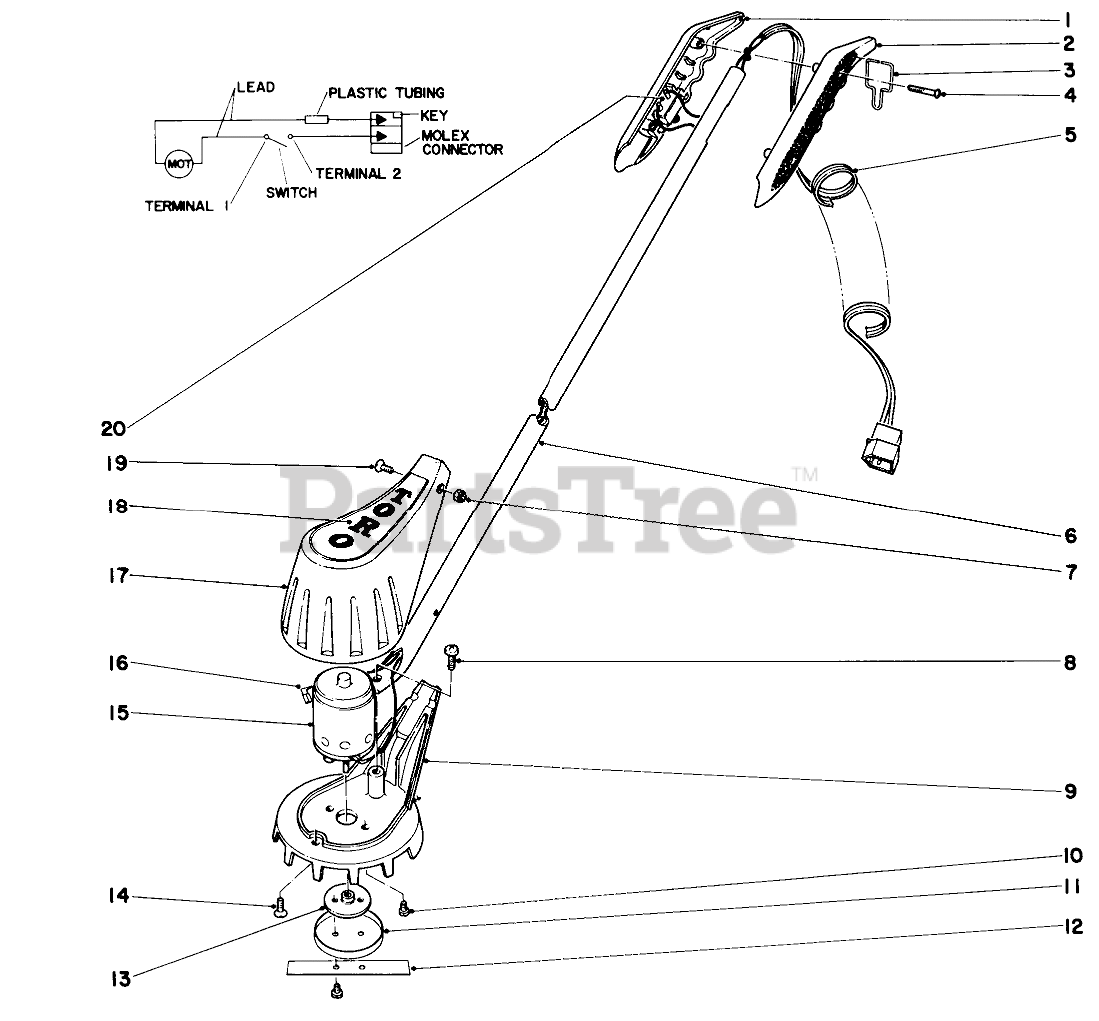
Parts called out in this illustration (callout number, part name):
1	Handle Trimmer Right Hand
2	Handle Trimmer Left Hand
3	Ring Hanger
5	Cord Assembly
6	Tube Handle
7	NUT-HEX
9	Trimmer Lower Housing
11	Grass Cup
12	Blade
13	Blade Retainer
15	Motor Trimmer
16	Lead Wire
17	Trimmer Upper Housing
18	Decal
20	Switch
